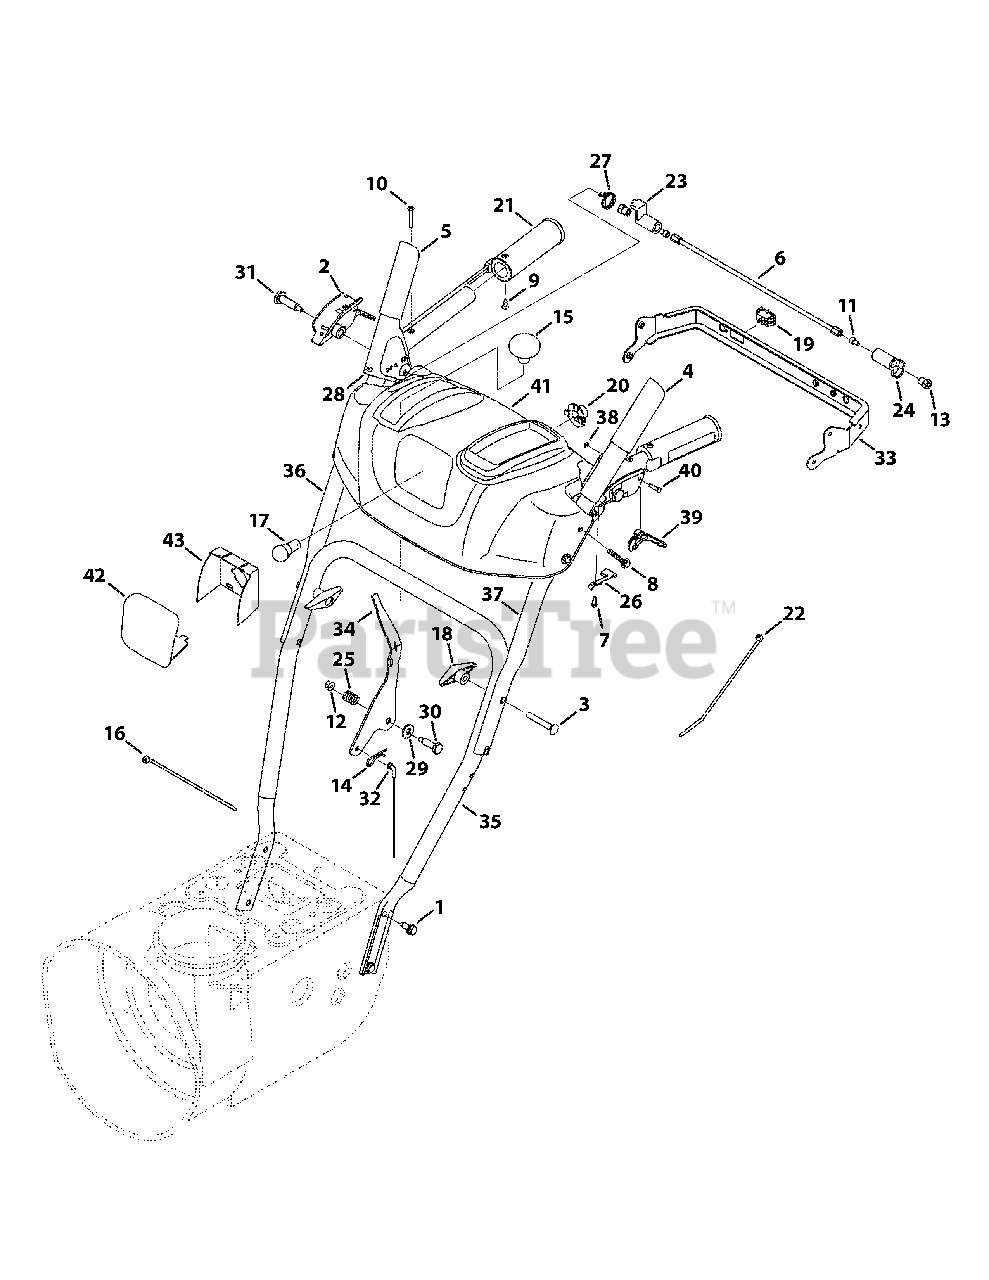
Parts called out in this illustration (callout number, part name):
1	Screw, Taptite, 5/16-18 x .750
2	Clutch Lock, RH
2	Clutch Lock, LH
3	Screw, Carriage, 5/16-18 x 2.25
4	Auger Engage, Red
5	Drive Engage, Red
7	Screw, Plastite, 8-16 x .50
8	Screw, Taptite, 1/4-20 x 1.625
9	Screw, 10-16 x 0.625
10	Screw, 10-24 x 1.375
11	Screw, 1/4-20 x .50
12	Nut, Flangelock, 1/4-20
13	Nut, Hex, 1/4-20
14	Click Pin, .092 x 1.64
15	Shift Knob
16	Cable Tie, 7"
17	Lamp, 12.5V
18	Star Knob, 5/16-18
19	Heated Grip Switch
20	Lamp Socket
21	Heated Grip
22	Cable Tie, Push Mount, 7.5 LG
23	Plate, Lock
24	Cam, Clutch Lock
25	Compression Spring, .39 x .60 x .88
26	Clutch Lock Spring
27	Torsion Spring, 0.8156 x .3038
28	Rubber Bumper
29	Washer, Flat, .385 x .87 x .06
30	Screw, Shield, .374 x 1.05
31	Screw, Shoulder, .437 x 1.345 x 1/4-20
32	Speed Selector Cable
33	Panel Bracket
34	Shift Lever
35	Lower Handle - Flint Mica
36	Upper RH Handle - Flint Mica
37	Upper LH Handle - Flint Mica
39	Steering Trigger Control, Red
40	Steering Trigger Pin, 3/16
41	Handle Panel, Troy-Bilt
42	Lens Panel
43	Lens Label
